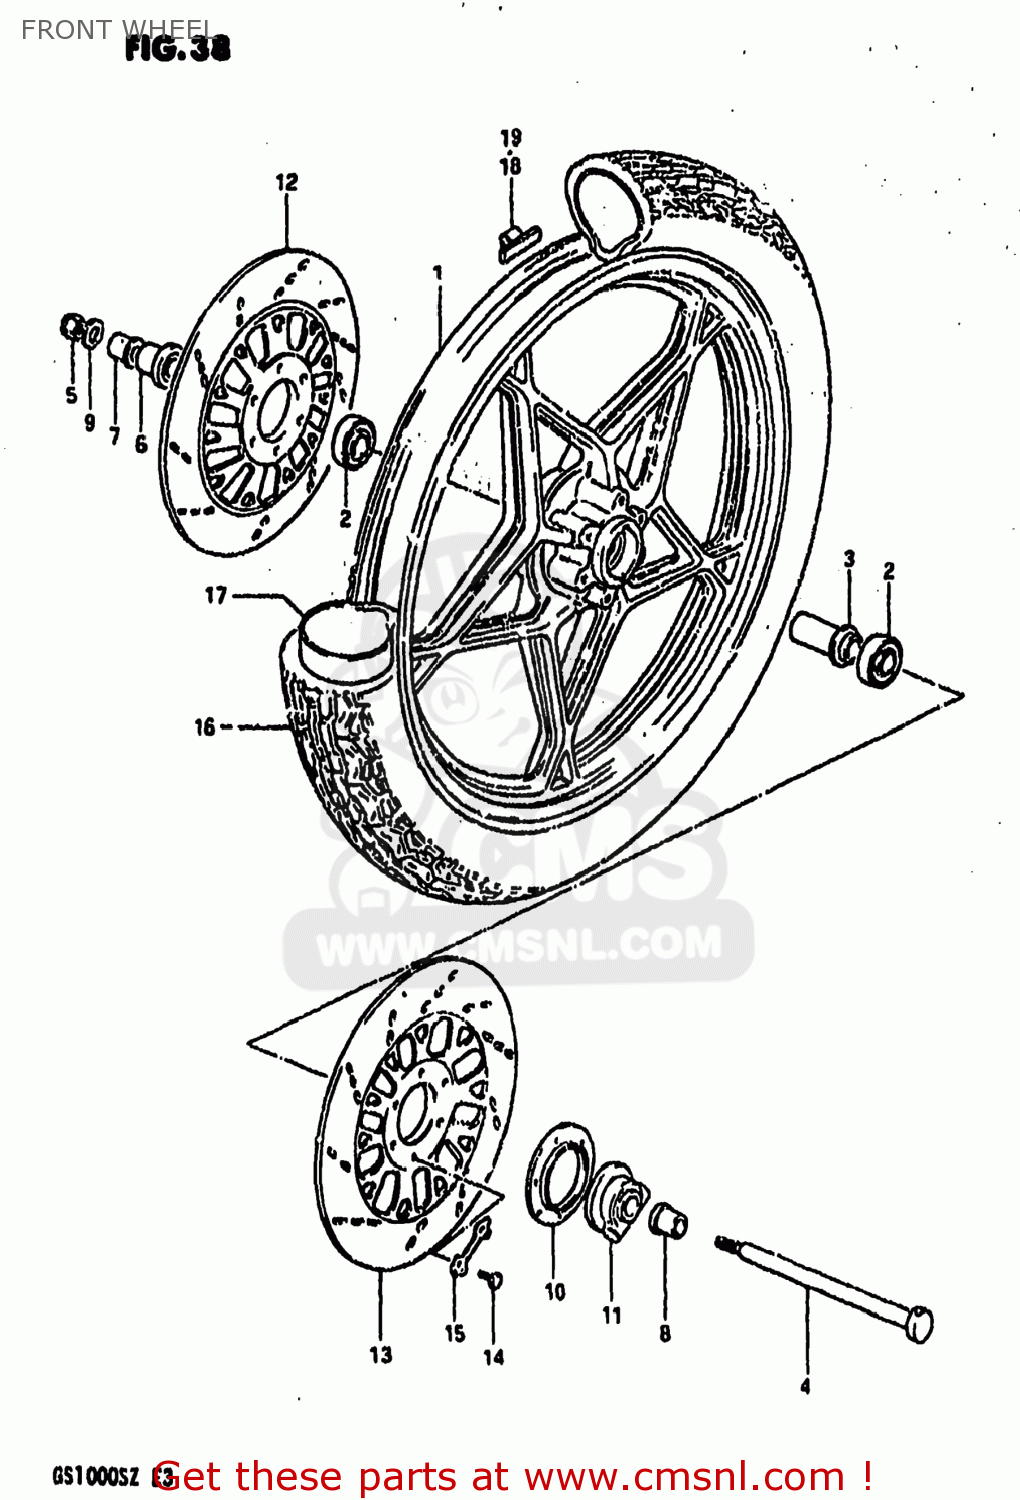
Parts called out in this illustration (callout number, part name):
1	WHEEL, FRONT (19*1.85)
2	BEARING
3	SPACER,FR HUB BEARING
4	AXLE,FR
5	NUT
6	SPACER,FR AXLE,R
7	SPACER,FR AXLE,R
8	SPACER,FR AXLE,L
9	WASHER
10	DUST SEAL,SPEEDOMETER GEAR BOX
11	BOX ASSEMBLY,SPEEDOMETER GEAR
12	DISC,FR BRAKE,R
13	DISC,FR BRAKE,L
14	BOLT(8X25)
15	WASHER
16	TIRE 3.50V19
17	TUBE,INNER
18	BALANCER,WHEEL
19	BALANCER,WHEEL (30G)
